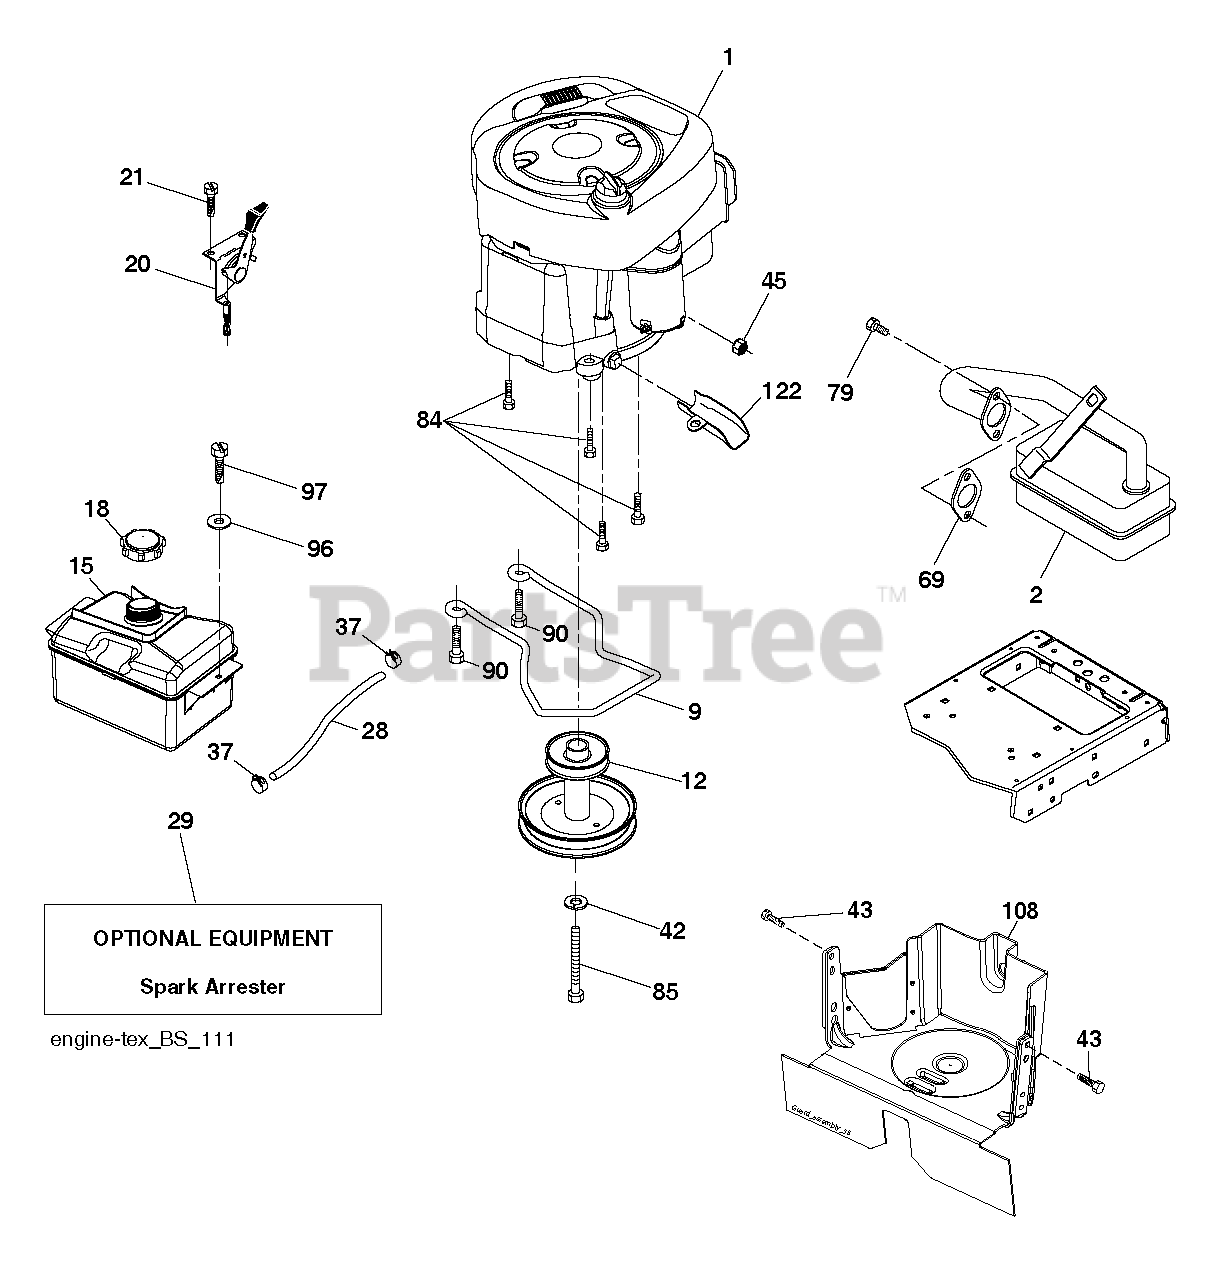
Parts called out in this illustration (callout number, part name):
2	MUFFLER.B&S.MODEL.21.11HP.OHV
9	KEEPER.BELT.ENG.4.25"2.BLT.431
12	ENGINE.PULLEY
15	FUEL.TANK.ASM.NON-EPA
18	CAP ASM.FUEL.2.25"FR.
20	CONTROL.TH/CK.C.
21	SCREW.#10 X 0.750.BOS
28	LINE.FUEL.20
29	KIT.SPARK ARRESTOR 794945 B&S
37	HOSE CLAMP
42	LOCKWASHER
43	SCREW 5/16-18X1
45	NUT
69	REPL BY 532 27 22-93
79	SCREW.SOCKET HD.5/16-1
84	SCREW.3/8-16
85	BOLT.HEX.7/16-20X4.GR5.1.5BLUE
90	SCREW 3/8-16X1
97	SCREW HEXWSHR 1/4-20X3/4
108	COVER.PULLEY.ENGINE.W
122	EXTENSION DRAIN OIL
